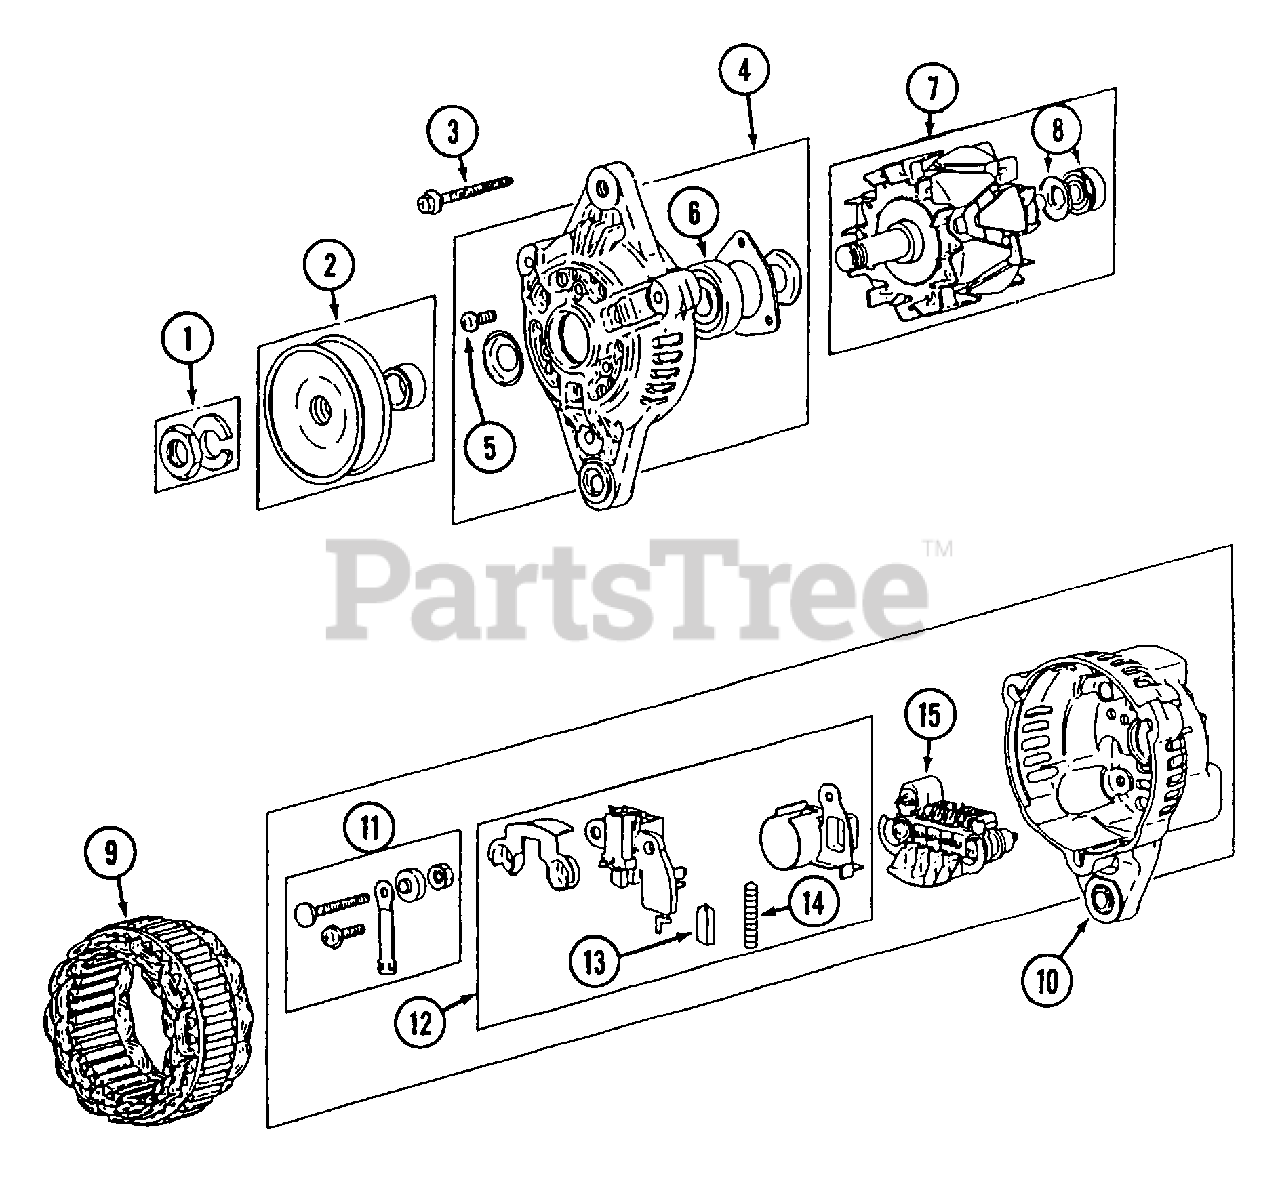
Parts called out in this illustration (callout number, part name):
4	Bracket Ass'y., Front
6	Bearing, Front
7	Rotor Ass'y.
8	Bearing, Rear
9	Starter Ass'y.
10	Bracket Ass'y., Rear
11	Terminal Set
12	Regulator Ass'y.
14	Spring, Brush
15	Rectifier Ass'y.
